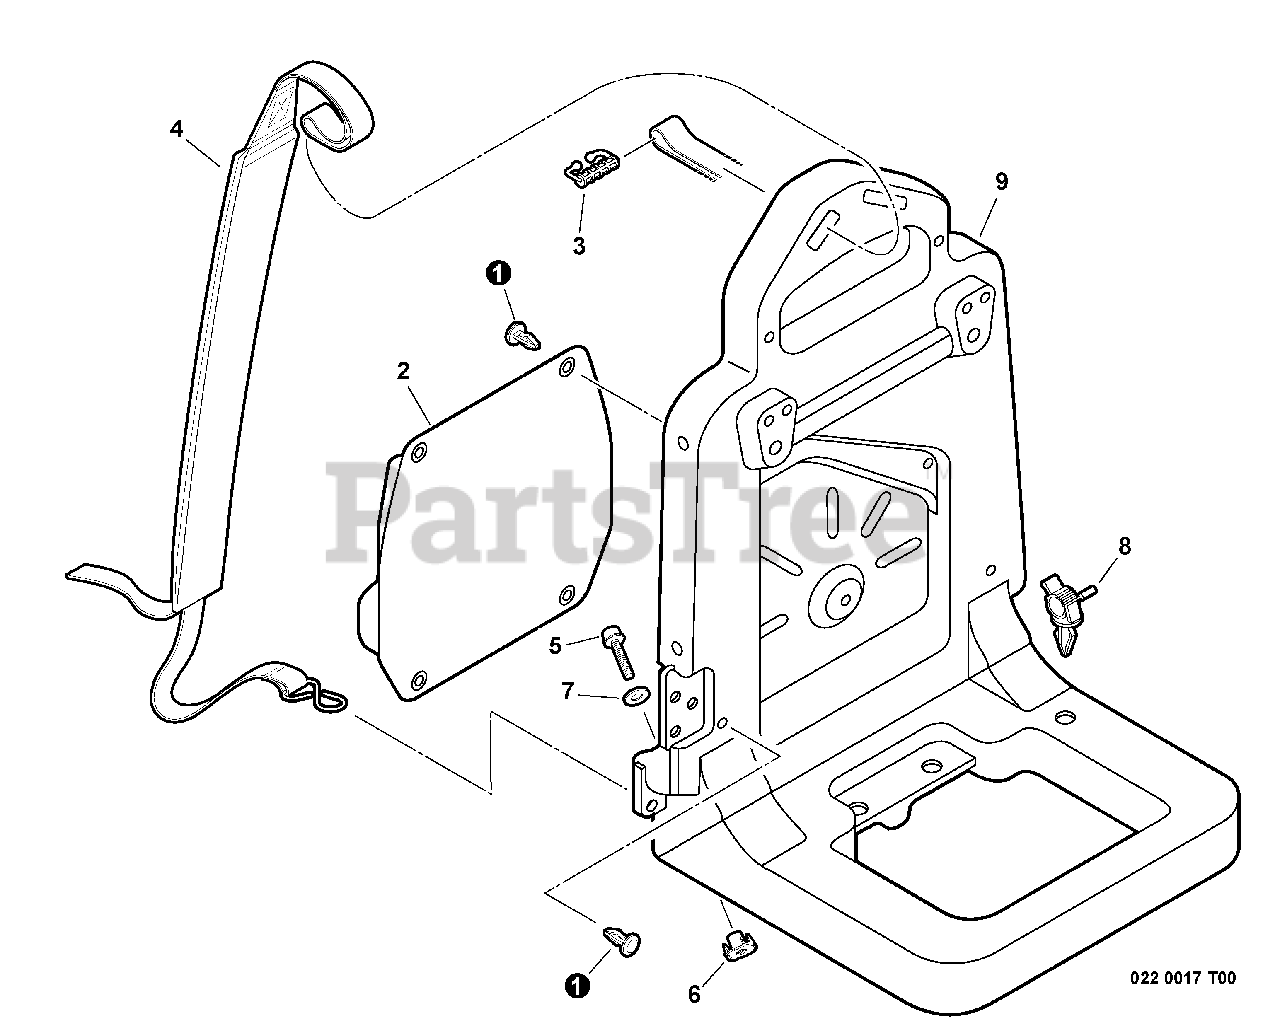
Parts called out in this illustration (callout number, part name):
2	CUSHION, BACKPACK
3	RETAINER, HARNESS
4	BACKPACK STRAP ASSY
5	SCREW - 6X25
7	WASHER - 6
8	CLIP, CABLE
9	FRAME, BACKPACK
